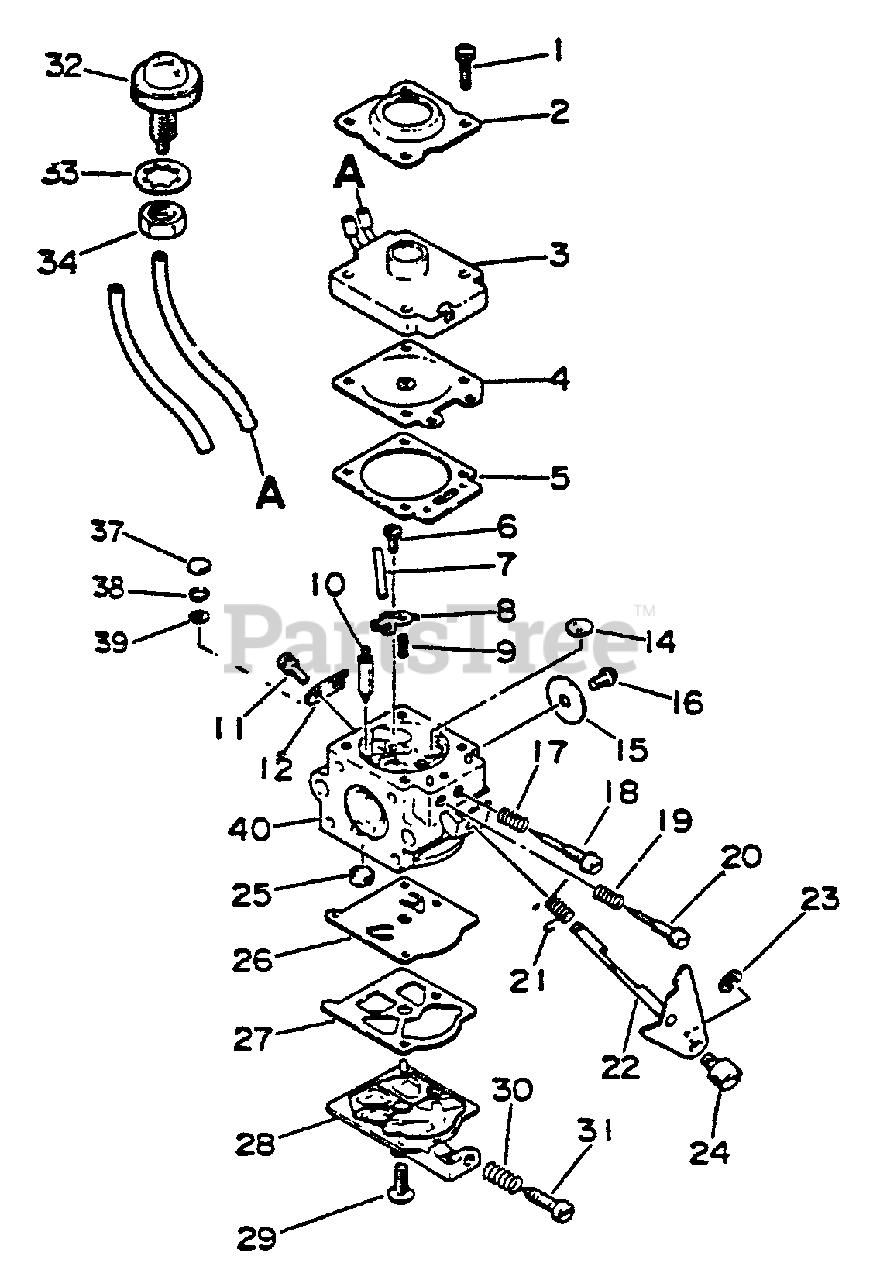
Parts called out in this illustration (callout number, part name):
1	SCREW
2	RETAINER, PURGE BULB
3	PURGE BASE ASSY
4	DIAPHRAGM, METERING
5	GASKET, METERING
6	SCREW, METERING LEVER PIN
7	PIN, METERING LEVER
8	LEVER, METERING
9	SPRING, METERING LEVER
10	VALVE, INLET NEEDLE
12	CLIP, THROTTLE SHAFT
14	PLUG, WELCH
15	VALVE, THROTTLE
17	SPRING, IDLE ADJUST
18	NEEDLE - LOW SPEED
19	SPRING, HIGH SPEED NEEDLE
20	NEEDLE - HIGH SPEED
21	SPRING, THROTTLE RETURN
22	SHAFT, THROTTLE
23	RING, RETAINING
25	STRAINER
26	DIAPHRAGM, PURGE
27	GASKET, PURGE
28	COVER, PUMP
29	SCREW, PUMP COVER
30	SPRING, IDLE ADJUST
31	SCREW, IDLE ADJUST
32	BASE, PURGE
33	LOCKWASHER - 10
34	NUT - 10
37	PLUG, WELCH
38	RING
39	STRAINER
40	BODY, CARBURETOR
